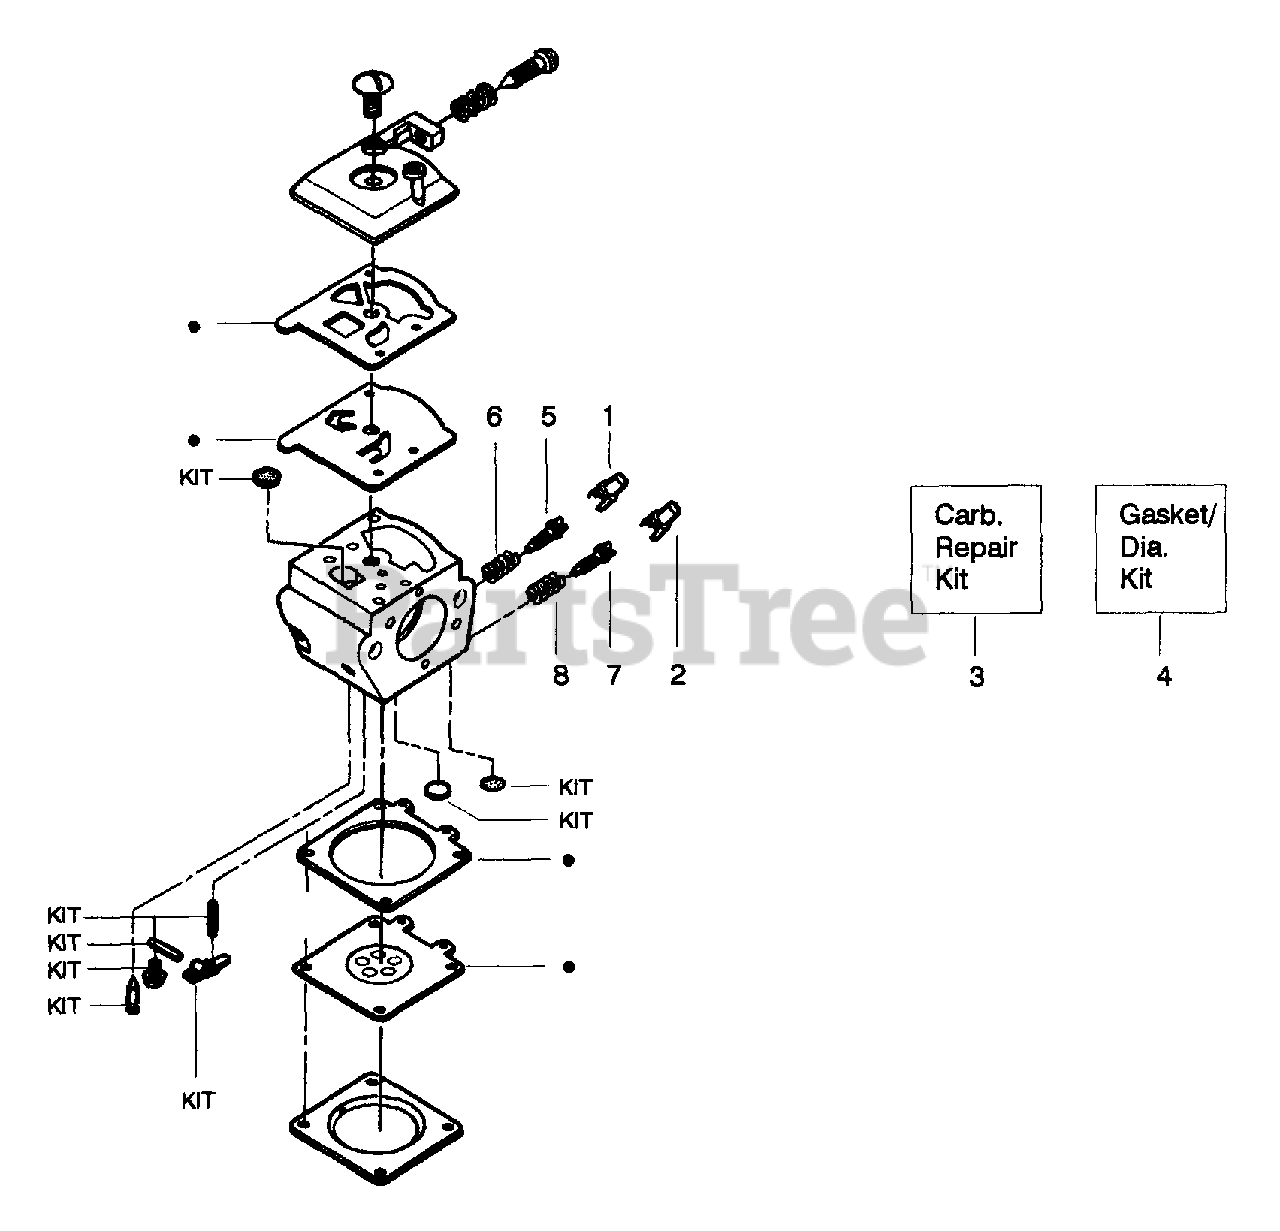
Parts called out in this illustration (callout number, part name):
1	Limiter Cap - High
2	Limiter Cap - Low
3	Carburetor Repair Kit
4	Gasket Diaphragm Kit
5	Needle - Low Speed
6	Needle Spring - Low Speed
7	Needle - High Speed
8	Needle Spring - High Speed
